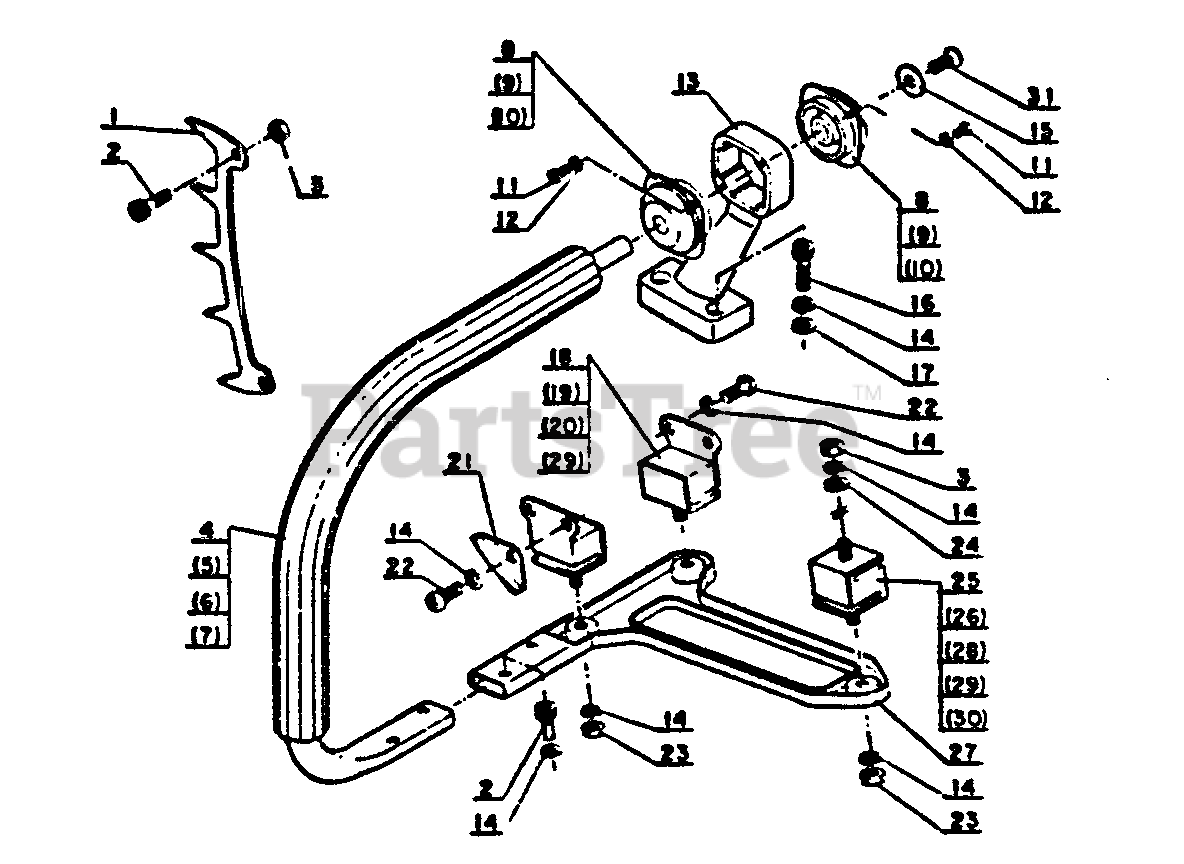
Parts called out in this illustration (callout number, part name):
1	SPIKE
2	BOLT - 5X12
3	LOCKNUT - 5
4	HANDLE - FRONT
8	Cushion rubber (L-U)
11	SCREW - 3X8
12	LOCKWASHER - 3
13	BRACKET, HANDLE - UPPER
14	LOCKWASHER - 5
15	WASHER
16	BOLT - 5X18
17	WASHER - 5
18	Cushion rubber (L-L)
21	PLATE
22	SCREW - 5X12
24	WASHER - 5
25	Cushion rubber (L-L: 2)
27	BRACKET, HANDLE - LOWER
31	SCREW - 5X12
